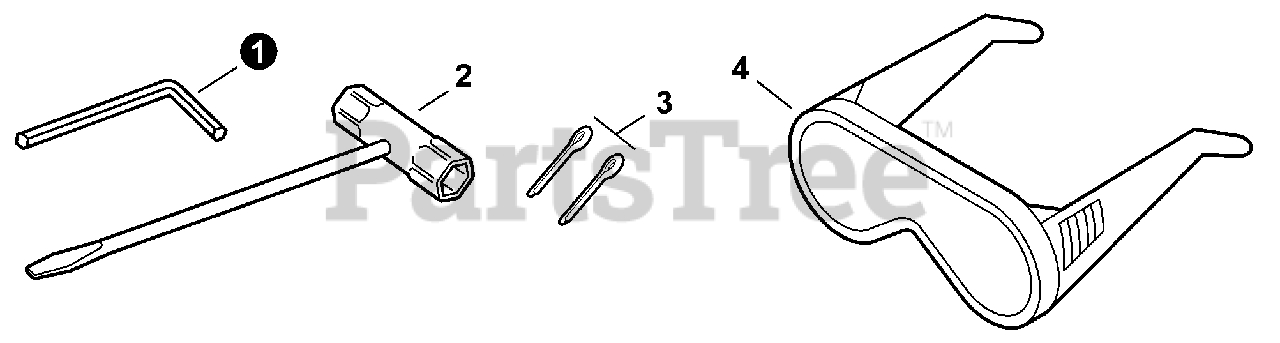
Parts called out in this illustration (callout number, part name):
1	WRENCH, ALLEN 4MM
2	T-WRENCH 17×19 L200
3	PIN, COTTER 2×22
4	GLASSES, SAFETY
